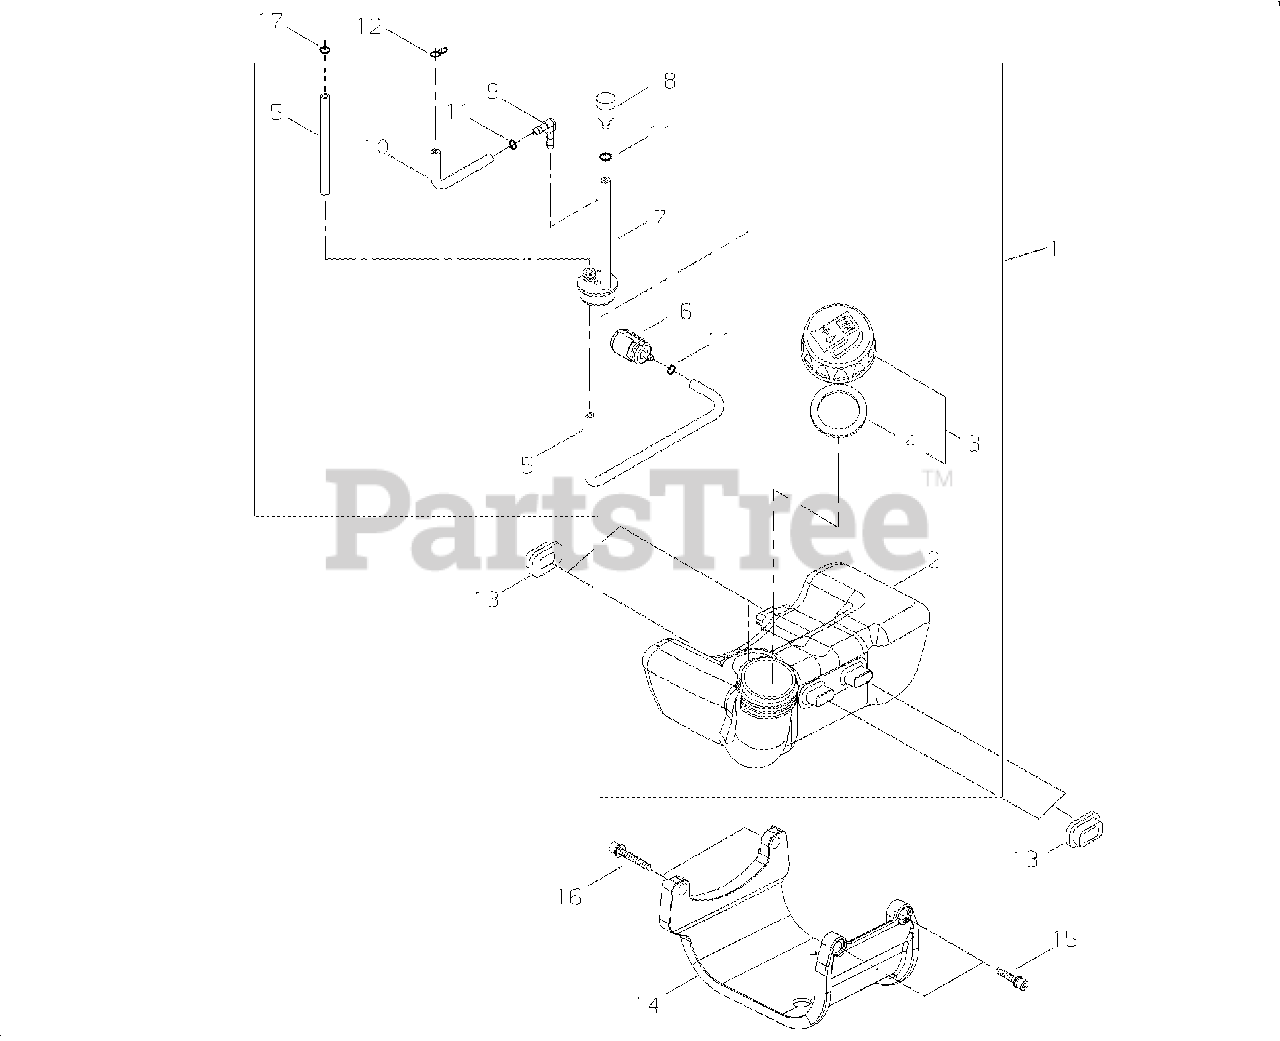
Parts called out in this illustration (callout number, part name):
1	FUEL TANK ASSY
2	TANK, FUEL
3	CAP ASSY
4	GASKET, CAP
5	PIPE - FUEL
6	FILTER, FUEL
7	PIPE ASSY
8	VENT, FUEL TANK
9	CONNECTOR, PIPE
10	PIPE - RETURN
11	RING, RETAINING - 6
12	CLIP - SPRING
13	CUSHION, FUEL TANK
14	GUARD, FUEL TANK
15	SCREW - 5X18
16	SCREW - 5X40
17	RING, RETAINING - 6
